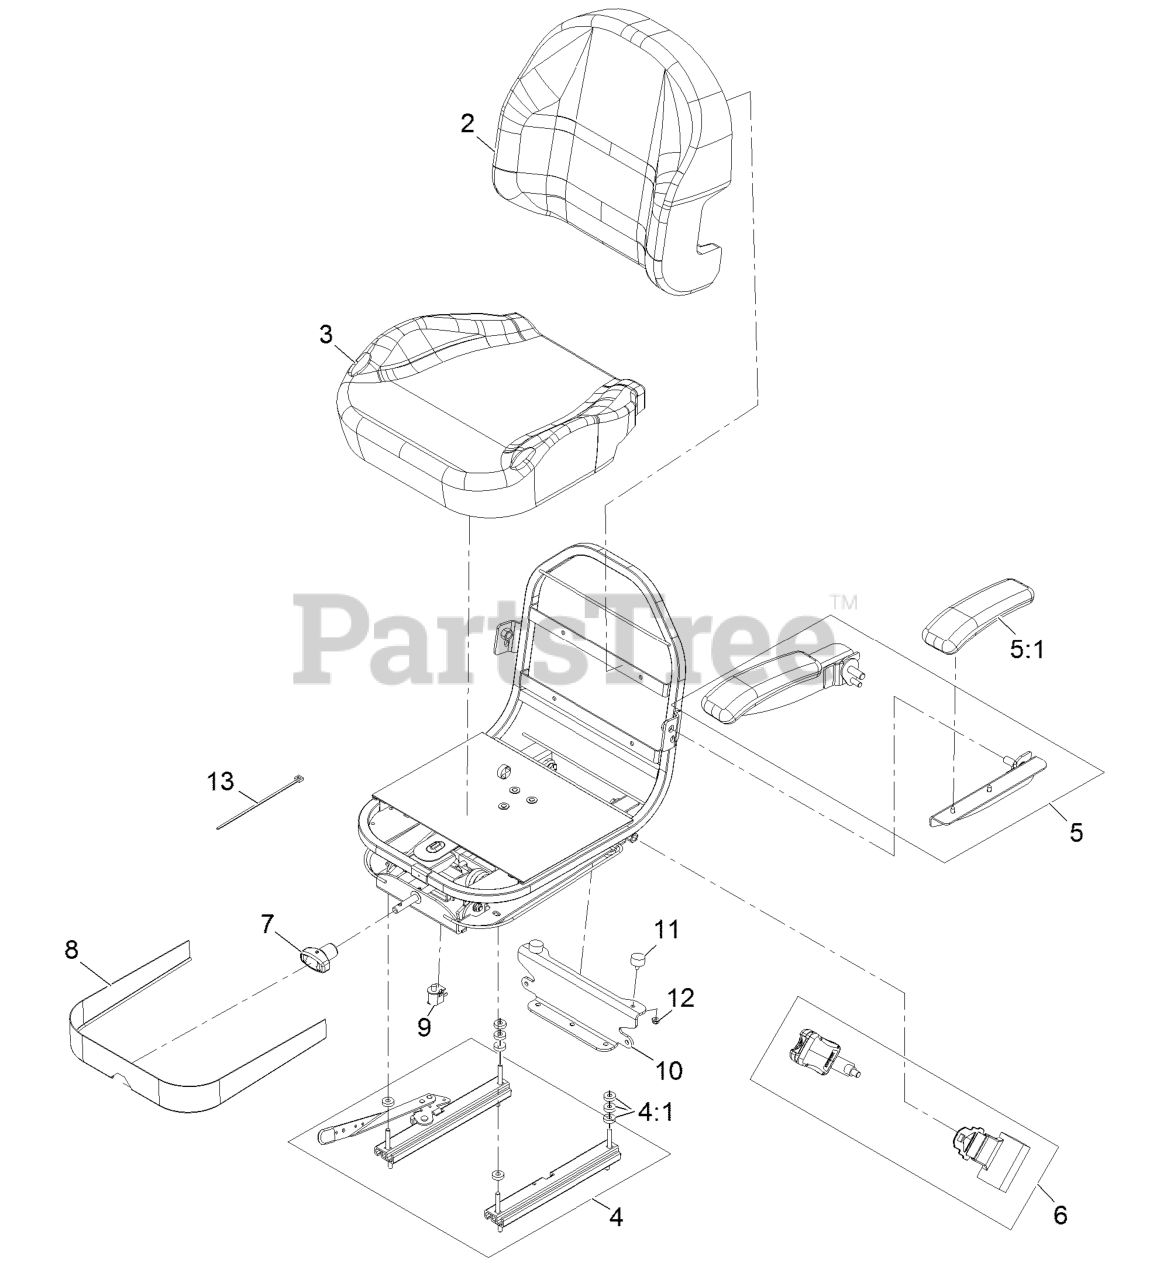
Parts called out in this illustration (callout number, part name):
2	COVER-SEAT BACK
3	COVER-CUSHION
4	KIT-TRACK-SEAT 4"
5	ARMREST KIT
5:1	CUSHION-REST, ARM
7	KNOB-ADJUSTER
8	COVER-SKIRT W/FASTENERS
9	SWITCH-BAIL
10	PLATE-SEAT SUPPORT
11	BUMPER-RUBBER
13	TIE-PLASTIC
